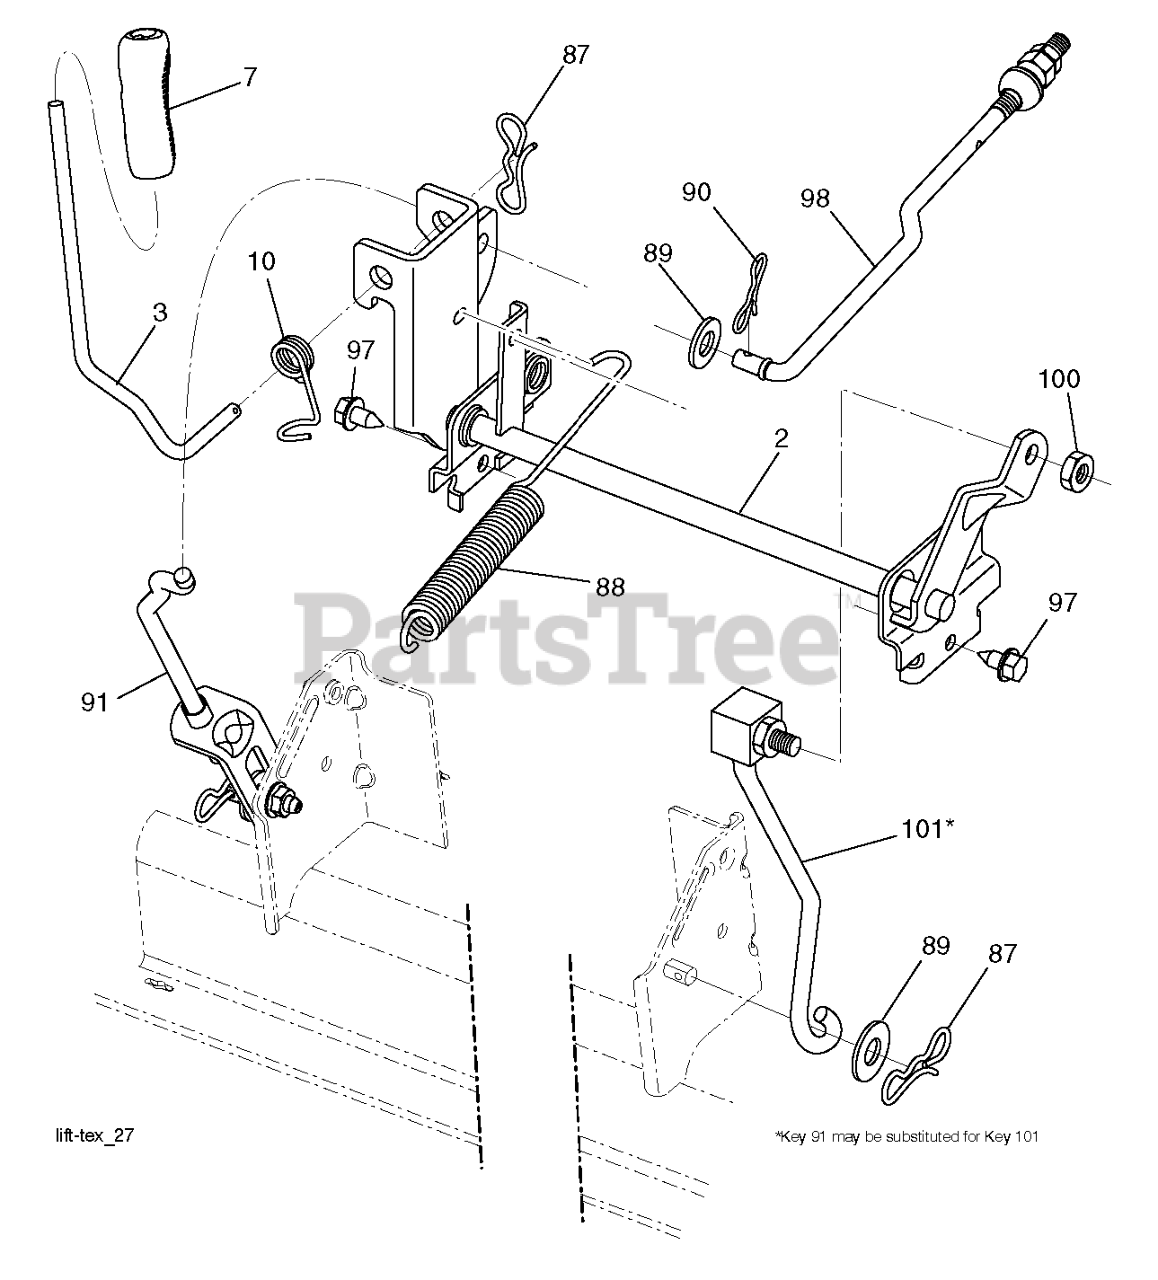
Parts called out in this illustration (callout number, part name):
2	SHAFT LIFT DECK WELD
3	LEVER.LIFT.HANDLE.LT
7	GRIP.HANDLE.LIFT.PVC.BLACK
10	SPRING.TORSION.LIFT.HANDLE
87	PIN.COTTER.7/16.BOW TI.
88	SPRING SPRING LIFT ASSIST 97
89	WASHER.CLEAR.ZINC
90	PIN.COTTER.5/16.BOW TI
91	LINK.ASM.LIFT.REAR
98	LINK.ASM.SUSP.FRONT.MW
100	LOCKNUT
101	LINK.ASM.LIFT.FIXE.38/42/46"
